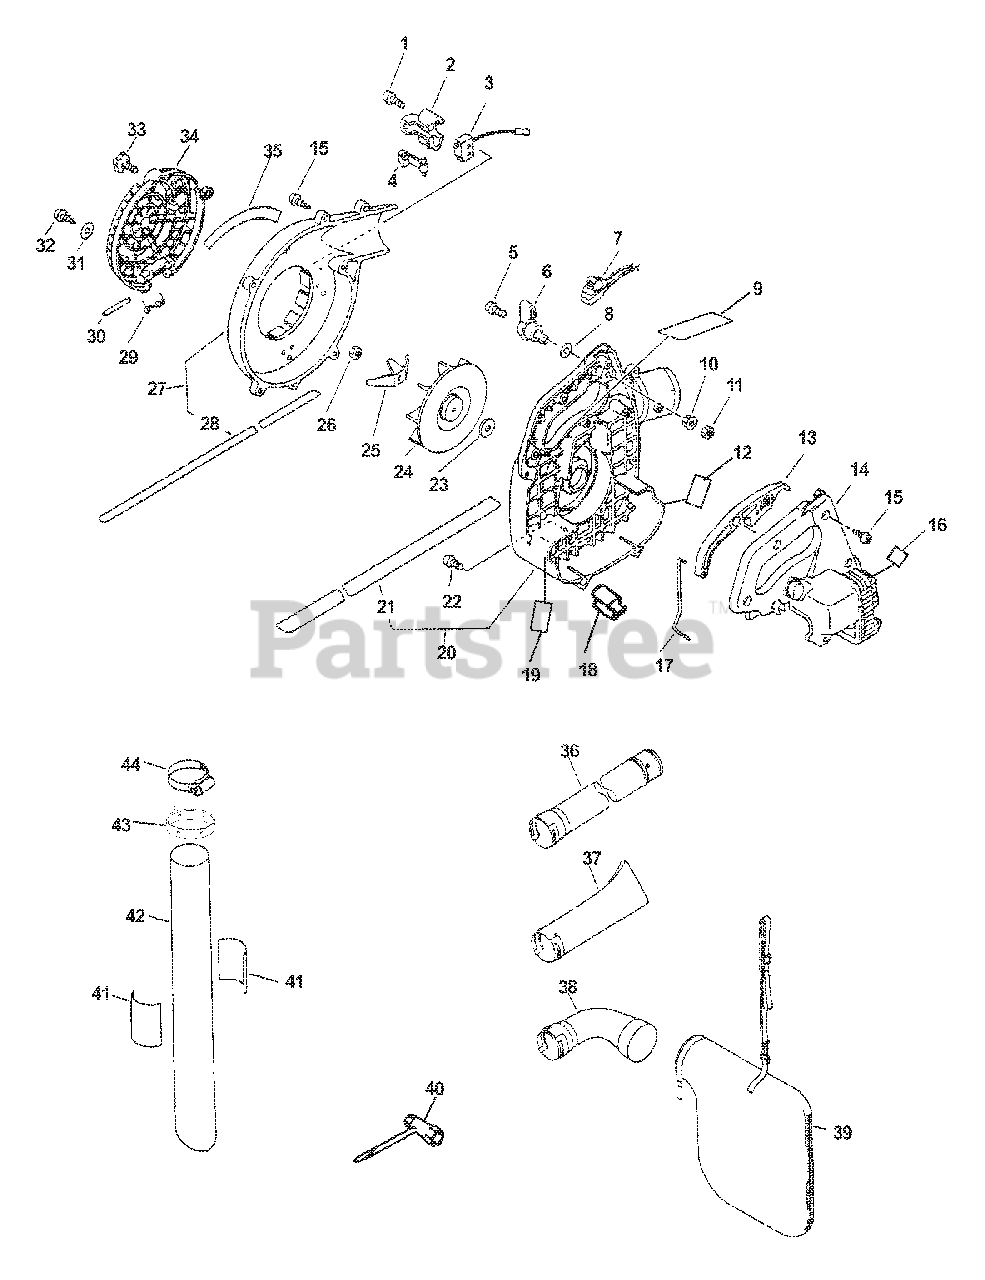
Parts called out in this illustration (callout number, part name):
1	SCREW - 4X22
2	BRACKET, SWITCH - GRAY
3	IGNITION SWITCH ASSY
4	LEVER, SHUT OFF ACTUATOR
5	SCREW - 5X25
6	LEVER, THROTTLE - ORANGE
7	IGNITION SWITCH ASSY
8	WASHER - 5
9	LABEL - CAUTION
10	NUT - 5 -- FLANGE
12	LABEL - CAUTION -- SPANISH
13	TRIGGER, THROTTLE - ORANGE
14	COVER, ENGINE
15	SCREW - 5X20 -- TAPPING
16	LABEL - HOT SURFACE
17	ROD, THROTTLE
19	LABEL - CAUTION
20	FAN COVER ASSY - RIGHT
21	CUSHION
22	SCREW - 4X22
23	WASHER - 8
25	BLADE, SHREDDER
27	FAN COVER ASSY - LEFT
28	CUSHION
31	WASHER - 5
32	SCREW - 5X14
33	THUMBSCREW
34	GUARD, DEBRIS
35	LABEL - MODEL ES-2100
36	TUBE, BLOWER - STRAIGHT
37	TUBE, BLOWER - NOZZLE
38	TUBE, DEBRIS
39	BAG, DEBRIS
40	T-WRENCH - 13X19mm
41	LABEL - SHRED 'N' VAC
42	TUBE, VACUUM
